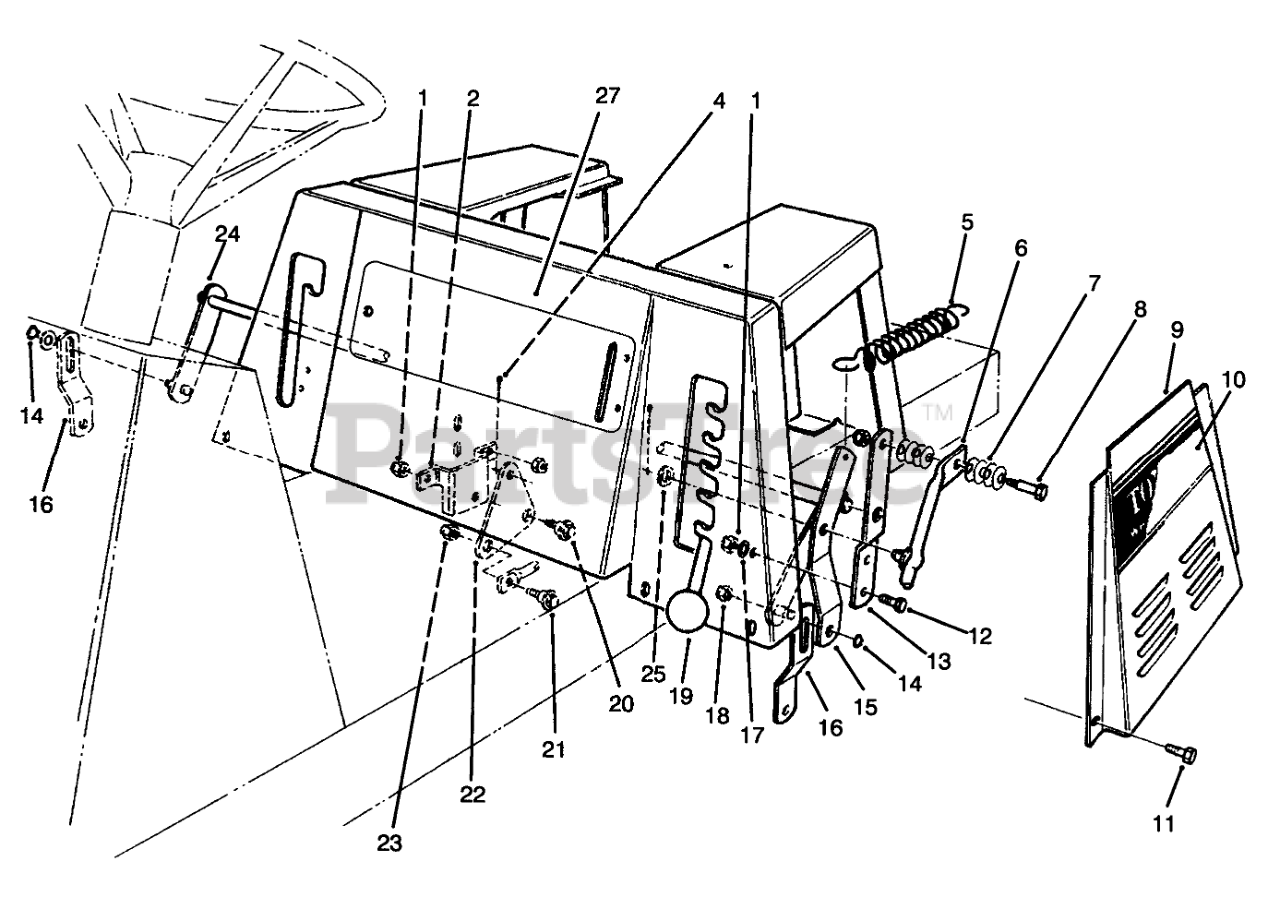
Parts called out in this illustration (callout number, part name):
1	NUT-LOCK, NI
2	BRKT-B.CRANK MTG
4	PIN-COTTER
5	SPRING-EXTENSION
6	HOC LEVER WA B
7	WASHER-BELLEVILLE
8	BOLT-SHOULDER
9	Panel L.H.-Base, Seat
10	DECAL - TORO 1232 LH
10	DECAL - TORO 1032 LH
11	SCREW-HH
12	SCREW-HH
13	Bracket
14	RING-RETAINING
15	Bracket-H.O.C., Engage
16	Link-Deck Suspension
17	WASHER-PLAIN
18	NUT-LOCK, NI
20	SCREW-SHOULDER
21	SCREW-SHOULDER
22	BELLCRANK
23	NUT-HEX
24	Arm
25	WASHER-FLAT
27	DECAL - CONTROL PANEL
